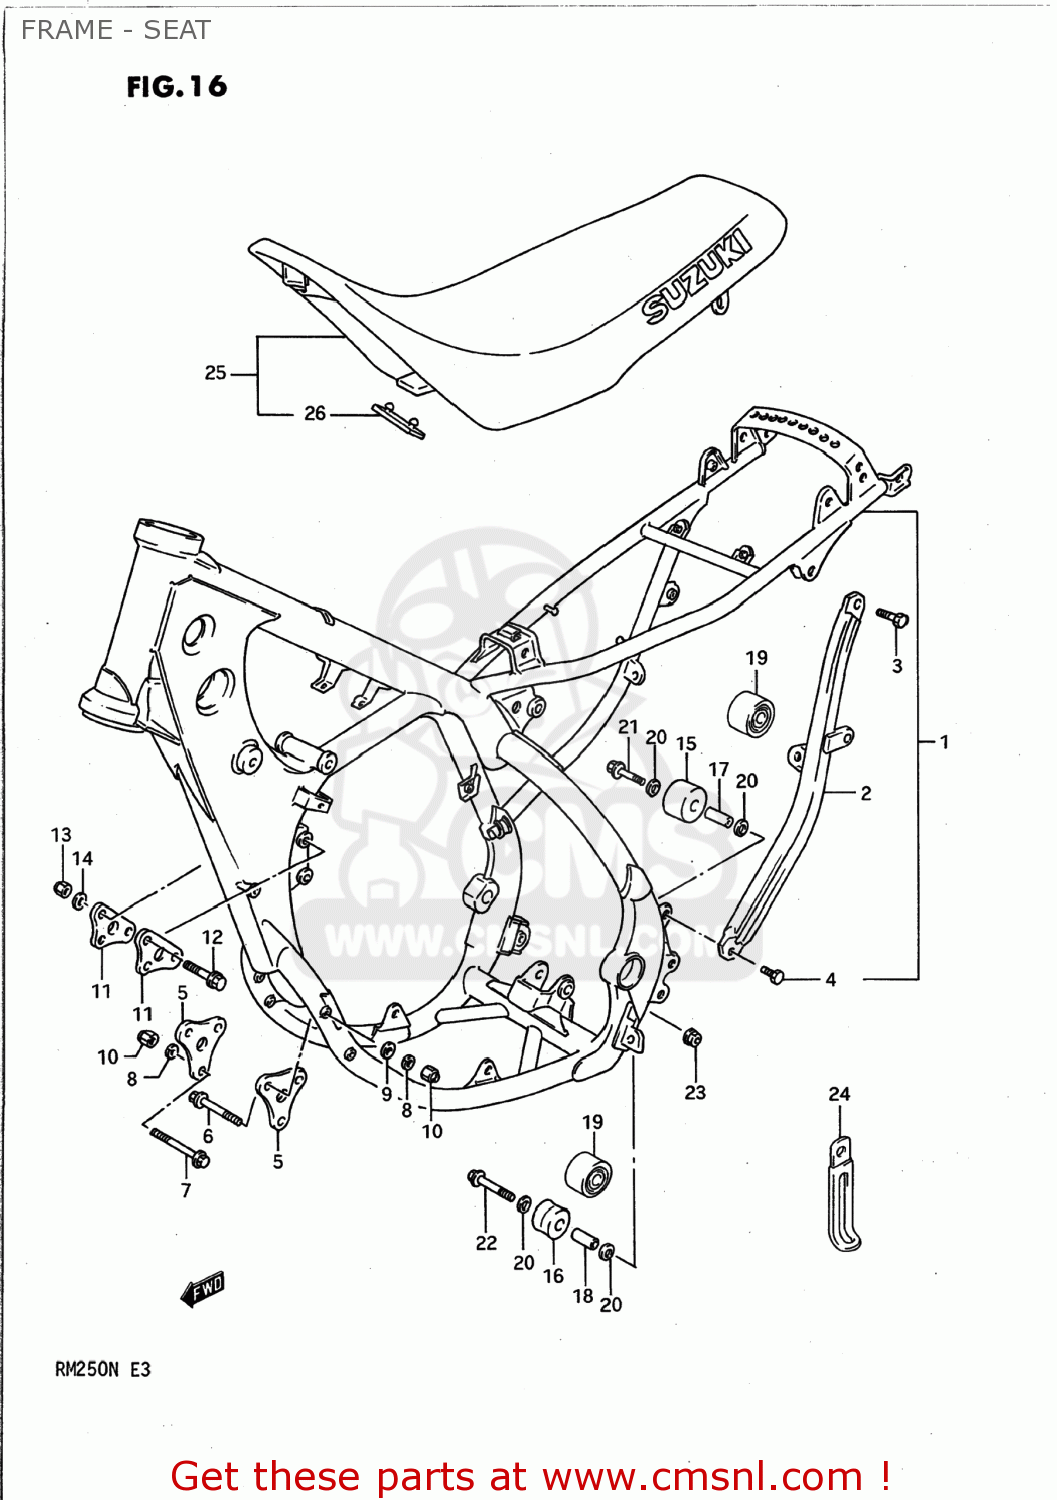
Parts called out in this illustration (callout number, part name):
1	FRAME SET
2	TUBE,FRAME SIDE,LEFT
3	BOLT
4	BOLT
5	PLATE,ENG MTG FR
6	BOLT
7	BOLT(8X60)
8	LOCK WASHER
9	WASHER
10	NUT
11	PLATE,ENGINE MOUNTING
12	BOLT
13	NUT
14	WASHER
15	ROLLER,CHAIN CONTROL
16	ROLLER,CHAIN CONTROL
17	SPACER (8.6X13.8X28)
18	SPACER(8.6X12X25.5)
19	ROLLER,CHAIN
20	WASHER
21	BOLT(8X41)
22	BOLT(8X45)
23	NUT
24	CLAMP
25	SEAT SET
26	CUSHION
